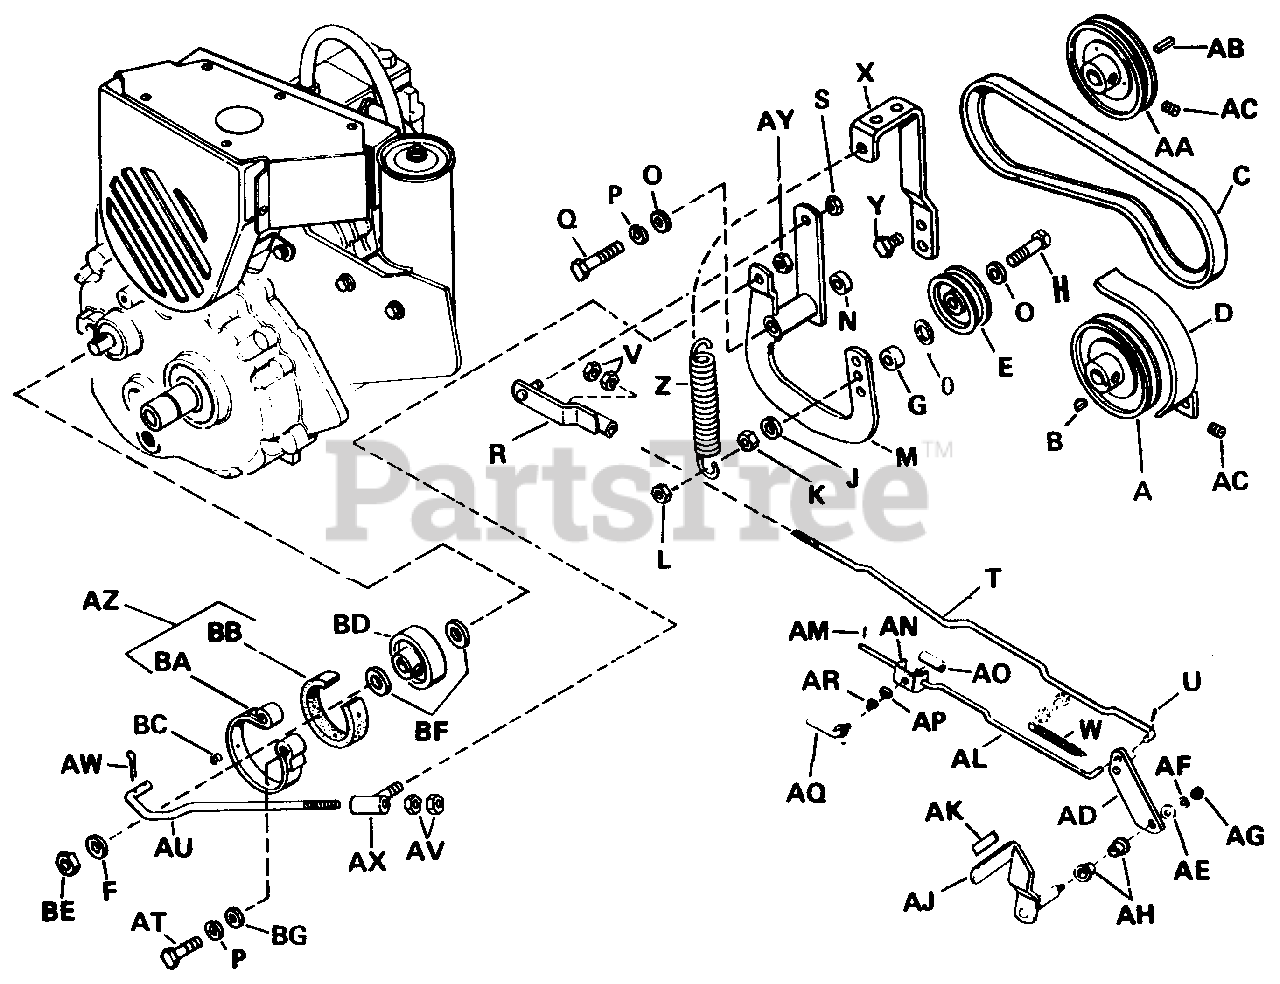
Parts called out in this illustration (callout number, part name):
A	Driver Pulley
B	Woodruff Key, 3/16" x 3/4"
C	BELT, A-Sect, 47.30
D	Belt Guard Assembly
E	Idler Pulley
F	Plain Washer, 3/8"
H	Hex. Capscrew, 3/8-16 x 2-1/4" lg.
J	Lock Washer, 3/8"
K	Full Hex. Nut, 3/8"-16 N.C.
L	Jam Hex. Lock Nut, 3/8"-16 N.C.
M	Idler Lever Assembly
O	Plain Washer, 3/8"
P	Lock Washer, 3/8"
Q	Hex. Capscrew, 7/16"-14 x 3-3/4"
R	Rod Guide Assembly,
S	Full Hex. Lock Nut, 5/16"-18 N.C.
T	Clutch & Brake Rod
U	Cotter Pin, 1/8" x 3/4" lg.
V	Full Hex. Nut, 5/16"-18 N.C.
W	Front Tension Spring
X	Spring Bracket, 1/4 x 1 x 11-1/4"
Y	Hex. Hd. Capscrew, 3/8 x 3/4"
Z	Idler Pulley Spring
AA	Driven Pulley
AC	Cup Pt. Socket Hd. Set Screw, 5/16-18 x 5/16"
AD	Food Pedal Arm, 1/4 x 1-3/4 x 5-7/8"
AE	Plain Washer, 3/8"
AF	Lock Washer, 3/8"
AG	Full Hex. Nut, 3/8"-16 N.C.
AJ	Foot Pedal Assembly
AK	Pedal Pad
AL	Parking Brake Rod
AM	Cotter Pin, 3/32" x 3/4" lg.
AN	Parking Brake Bracket Asset.
AO	Spacer, 3/8"
AP	Plain Washer, 7/16"
AQ	Parking Brake Lock
AR	Conical Spring
AT	Hex. Capscrew, 3/8"-16 x 1-3/4" lg.
AU	Brake Rod
AV	Full Hex. Nut, 3/8"-16 N.C.
AW	Cotter Pin, 3/32" x 3/4" lg.
AX	Rod Guide Assembly
AY	Full Hex. Lock Nut, 5/16"-18 N.C.
AZ	Brake Band & Lining Assembly
BA	Brake Band
BB	Brake Lining
BC	Rivet No. 7 x 1/4" lg.
BE	Lock Nut, 7/16"-14
BG	Plain Washer, 3/8"
